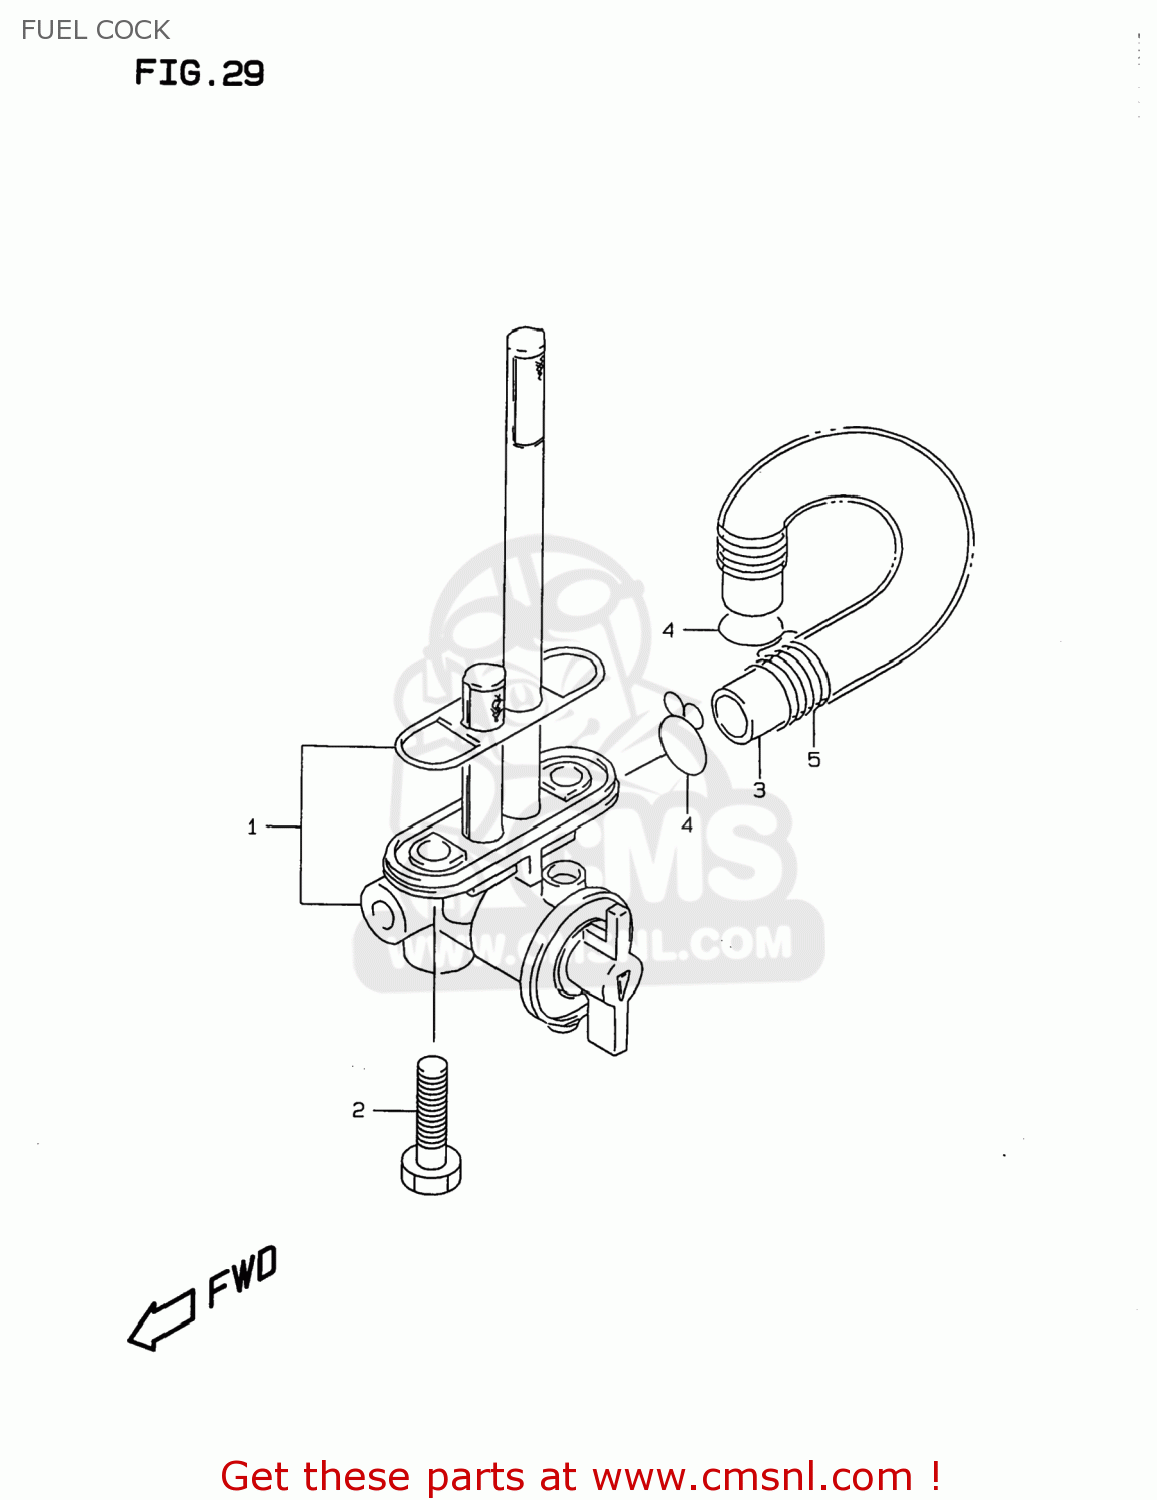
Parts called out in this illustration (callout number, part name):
1	COCK ASSY,FUEL
2	SCREW
3	HOSE(7X12X600)
4	CLIP
5	SPRING
